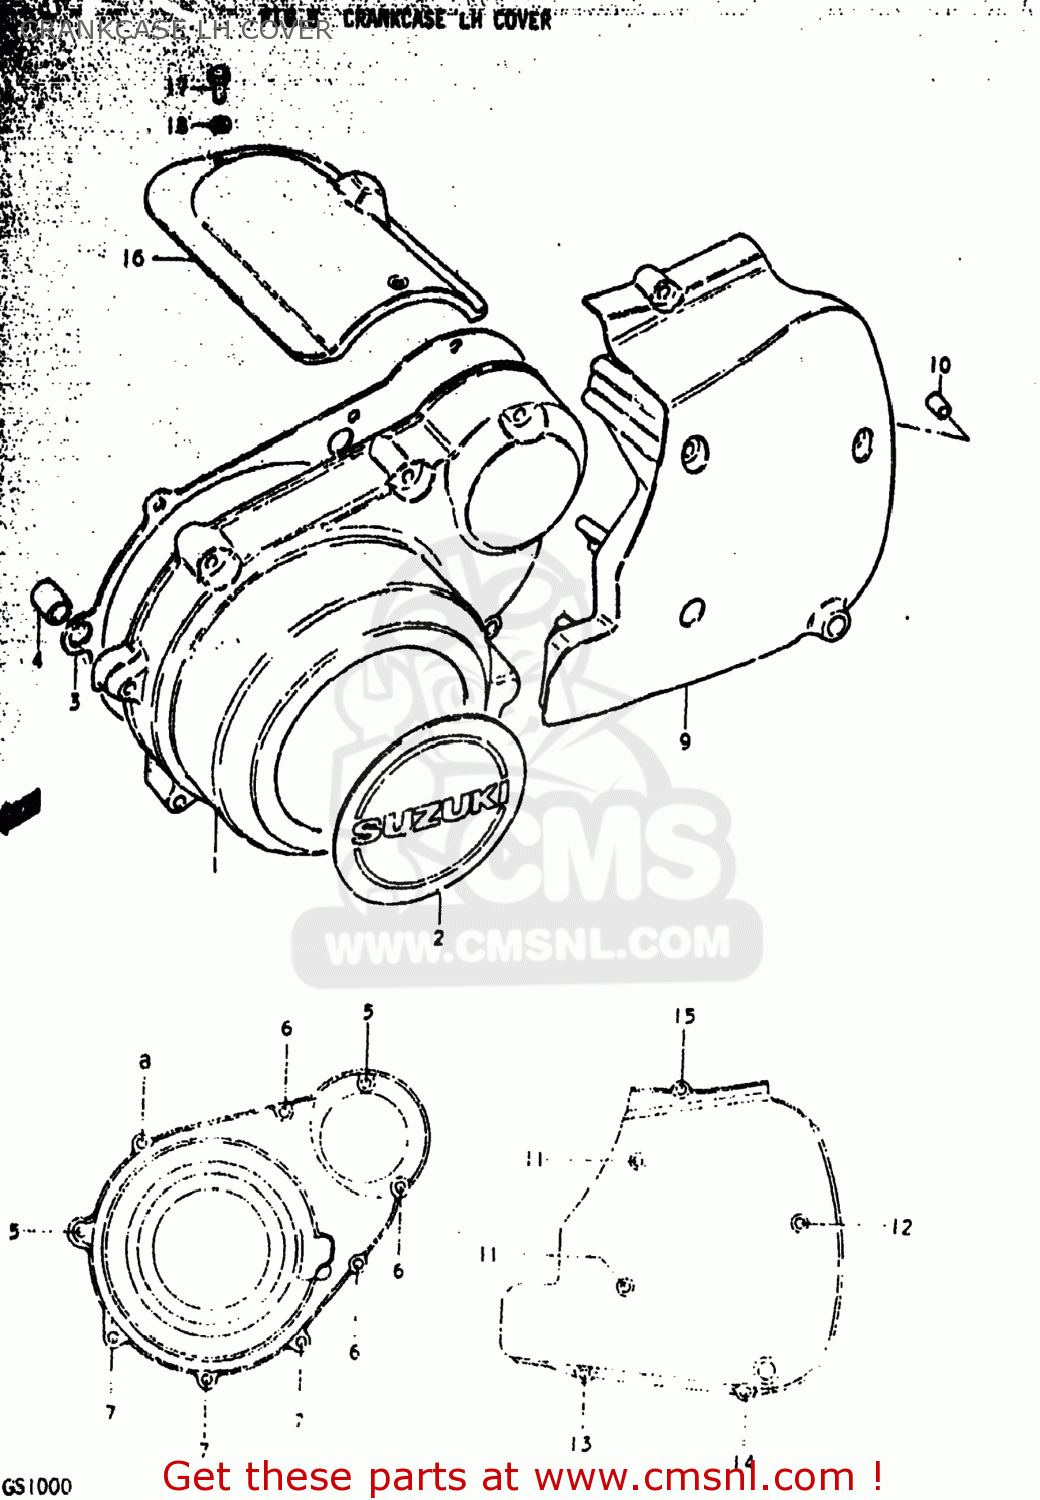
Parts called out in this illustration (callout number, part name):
1	COVER
2	EMBLEM
3	GASKET,MAGNETO COVER (MCA)
4	PIN
5	SCREW (6X45)
6	SCREW
7	SCREW (6X35)
8	SCREW
9	COVER,ENGINE SPROCKET
10	PIN
11	SCREW(6X100)
12	SCREW 6X85
13	SCREW 6X70
14	SCREW
15	SCREW
16	COVER,STARTER MOTOR
17	BOLT
18	WASHER
